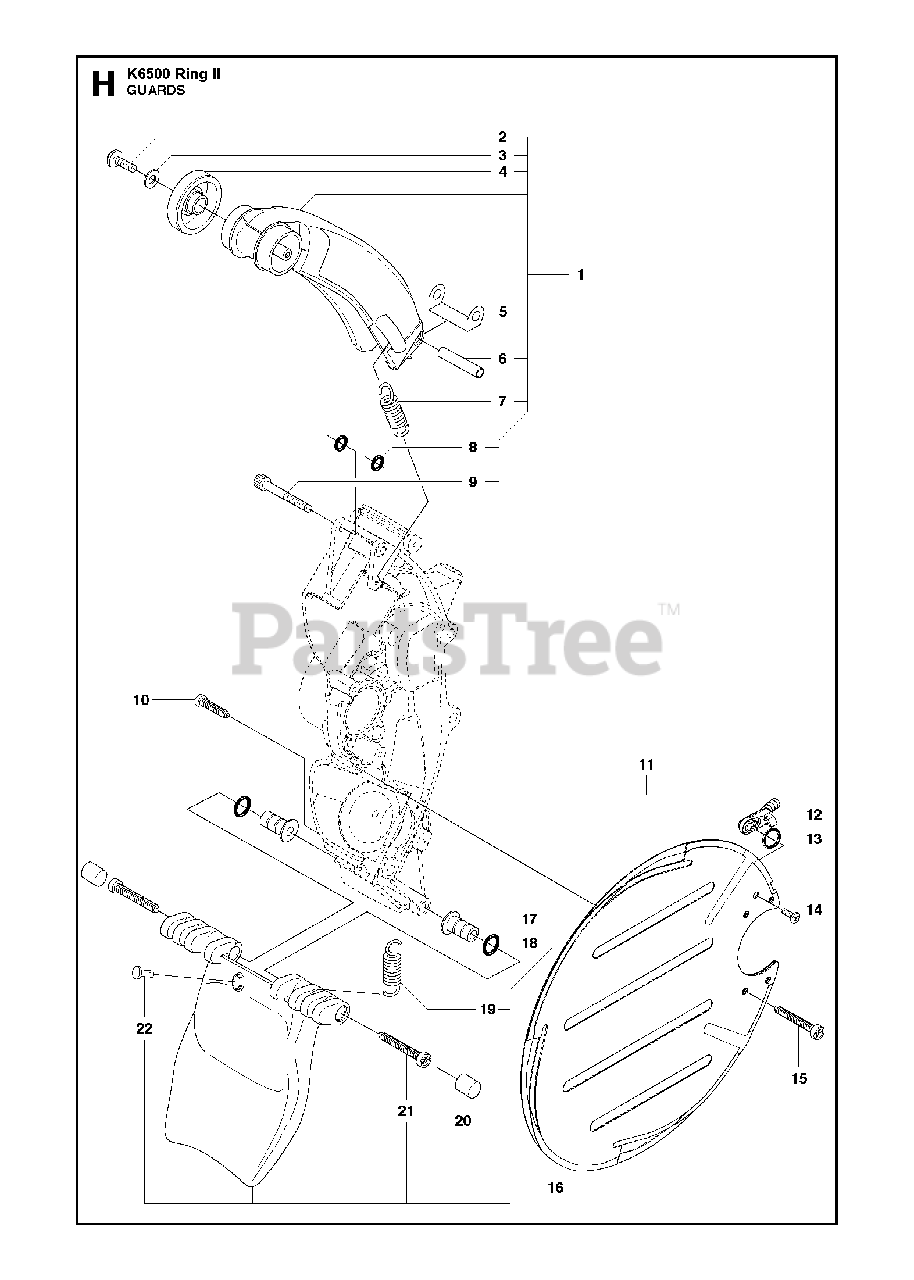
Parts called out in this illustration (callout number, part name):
6	SPACING TUBE
9	SCREW ITXSCM
10	SCREW ITXSCM
14	SCREW CRPANT
15	SCREW ITXSCM
21	SCREW ITXSCM
